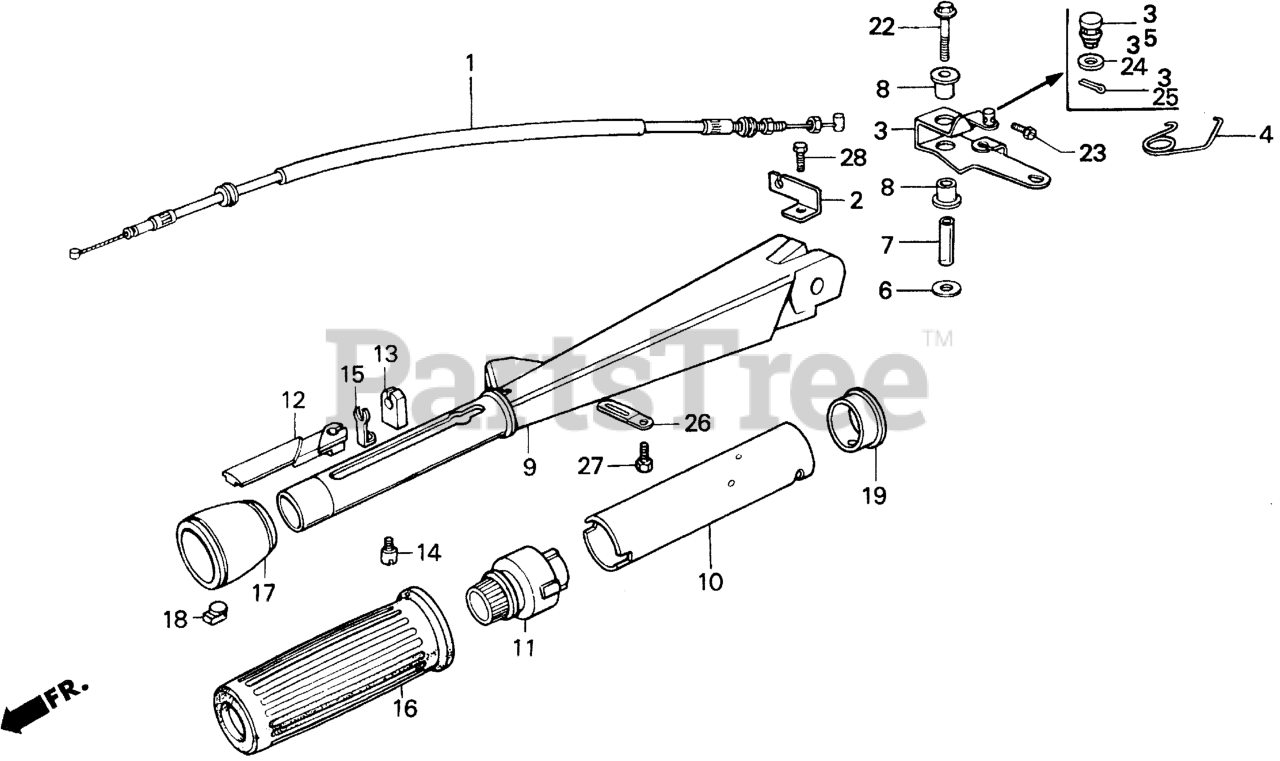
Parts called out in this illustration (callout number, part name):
1	CABLE, THROTTLE
2	HOLDER, CABLE
3	ARM, THROTTLE
4	SPRING, THROTTLE ARM
5	HOLDER, STARTER ROD
6	WASHER, PIVOT
7	COLLAR, PIVOT
8	BUSH, SHAFT
9	HANDLEBAR *B107* (SENIOR BLUE) (NOT AVAILABLE)
10	PIPE, GRIP (NOT AVAILABLE)
11	NUT, GRIP FRICTION
12	HINGE, THROTTLE WIRE
13	HOLDER, THROTTLE CABLE
14	STOPPER, GRIP PIPE
15	STOPPER, CABLE
16	RUBBER, GRIP
17	COVER, GRIP PIPE
18	GROMMET, HANDLE COVER
22	BOLT, FLANGE (6X35) (NOT AVAILABLE)
23	BOLT, STRAIGHT SLOT (4X6)
24	WASHER, PLAIN (6MM) Use from Frame SN 4800713.
25	PIN, SPLIT
25	PIN, SPLIT (2.0)
26	CLIP B, CORD
27	BOLT, HEX. (6X8)
28	BOLT, HEX. (6X12)
